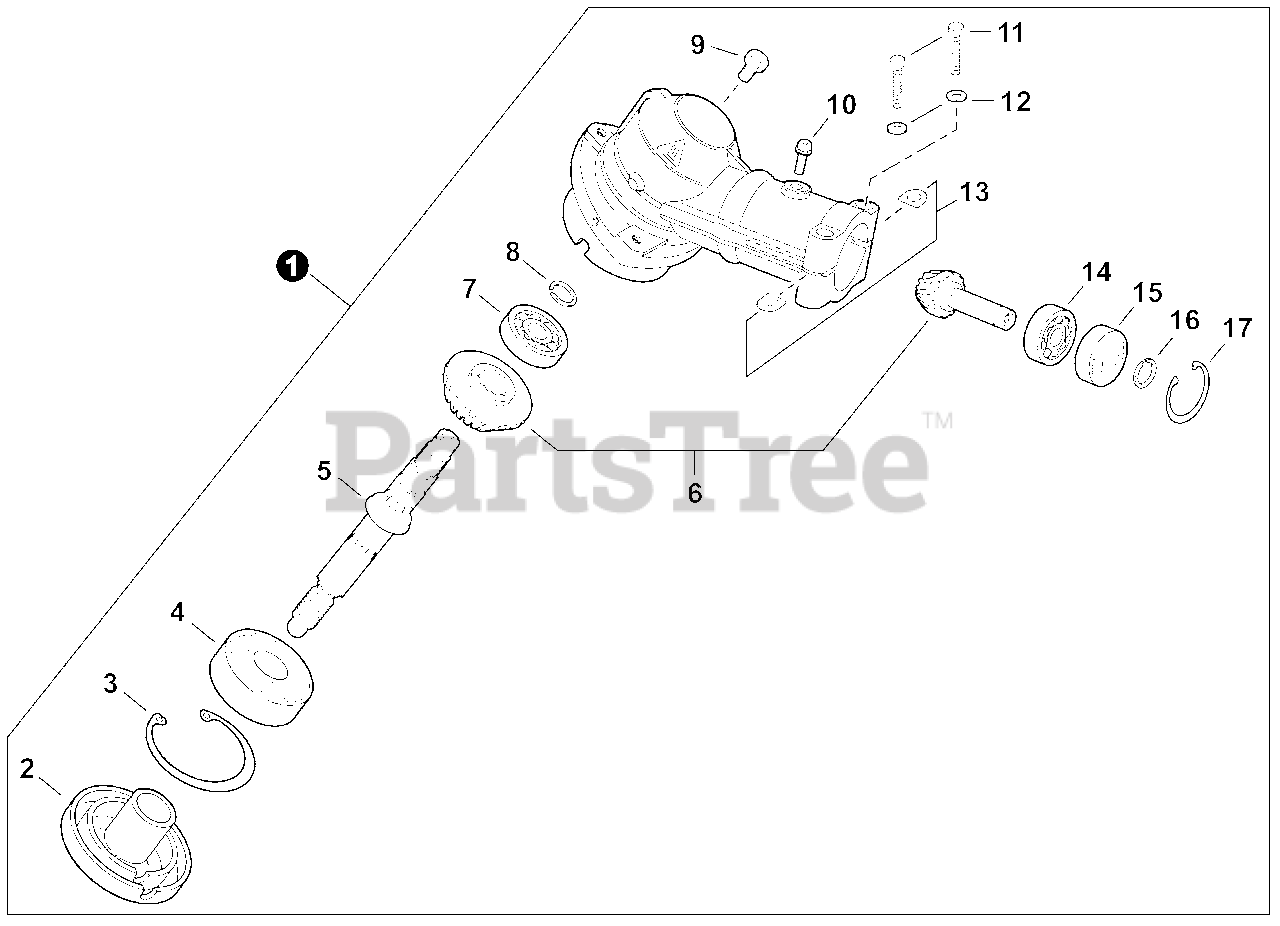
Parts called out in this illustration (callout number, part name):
1	GEAR CASE ASSY
2	PLATE, ADAPTOR - UPPER
3	RING, SNAP Ø42
4	BEARING, BALL 6302
5	SHAFT, GEAR
6	GEAR SET
7	BEARING, BALL 629
8	RING, SNAP Ø12
9	BOLT M8×8
10	SCREW 5×12
11	BOLT 5×35 SP
12	WASHER, FLAT 5.5×10×0.8
13	D-WASHER
14	BEARING, BALL 6900
15	BEARING, BALL 6900-Z
16	RING, SNAP Ø10
17	RING, SNAP Ø22
